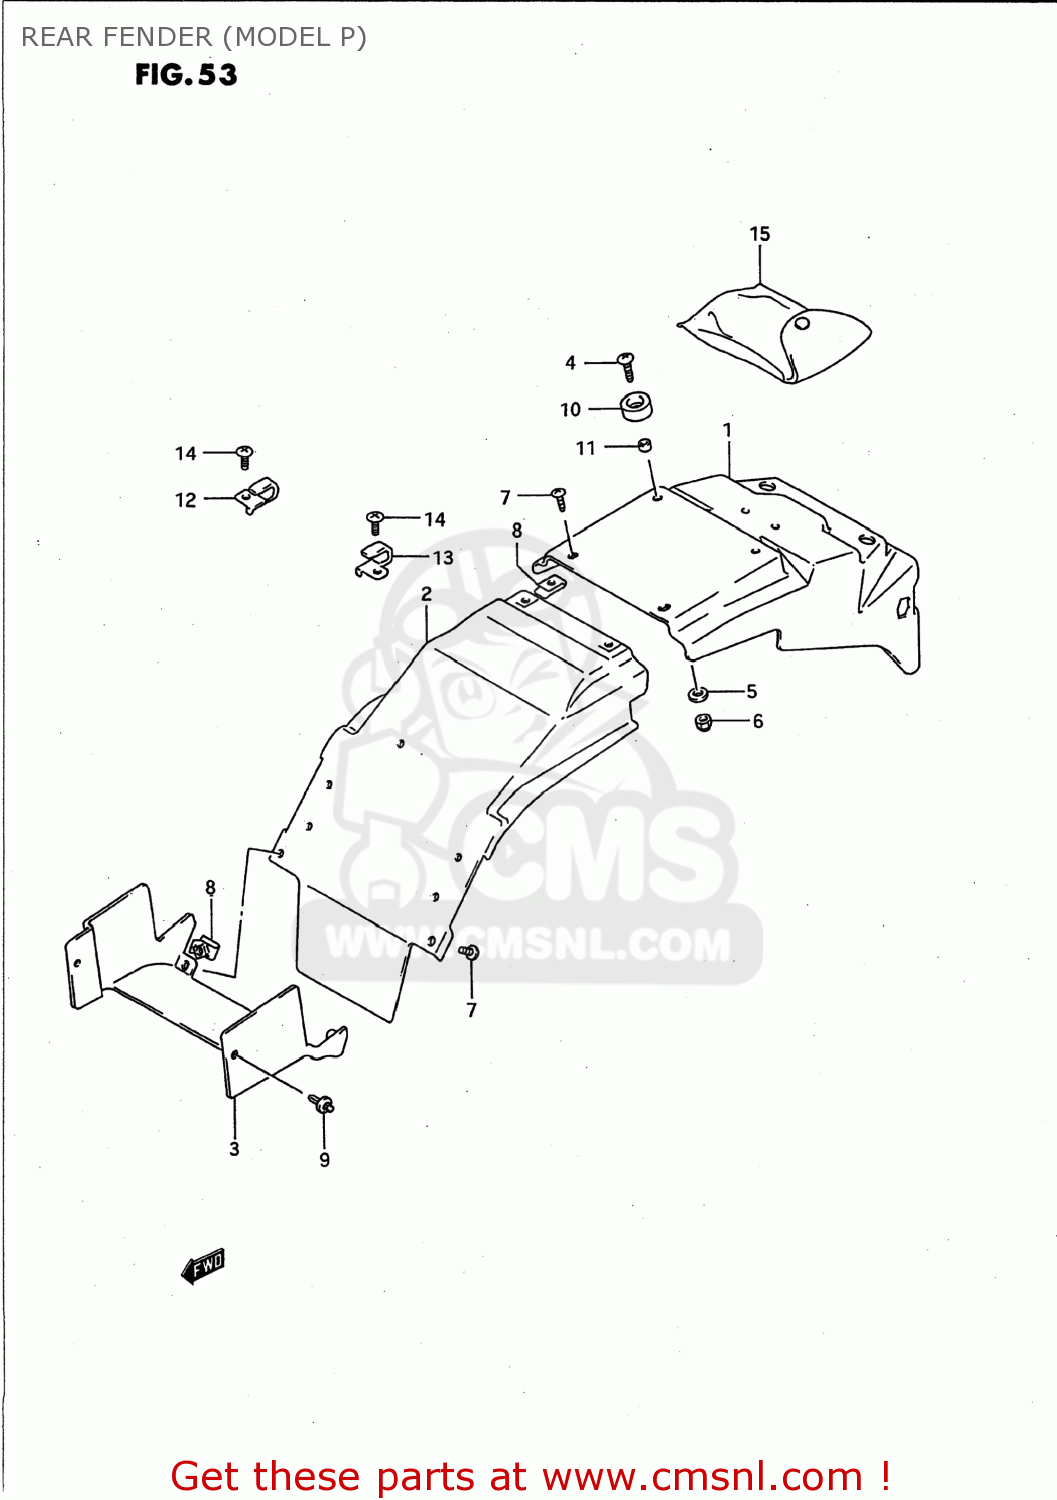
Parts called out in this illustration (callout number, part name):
1	FENDER,RR UPR
2	FENDER,REAR,UPPER,FRONT,N
3	FENDER,REAR,UPPER,FRONT,N
4	SCREW, CENTER
5	WASHER
6	NUT
7	SCREW, FRONT & REAR
8	NUT,HEADLAMP HOUSING,UPPER
9	CLIP
10	CUSHION,TAIL COVER UPR
11	SPACER (6.8X10X4.7)
12	HOLDER,HELMET,R
13	HOLDER,HELMET,LEFT
14	SCREW 6X12
15	TOOL ASSY
